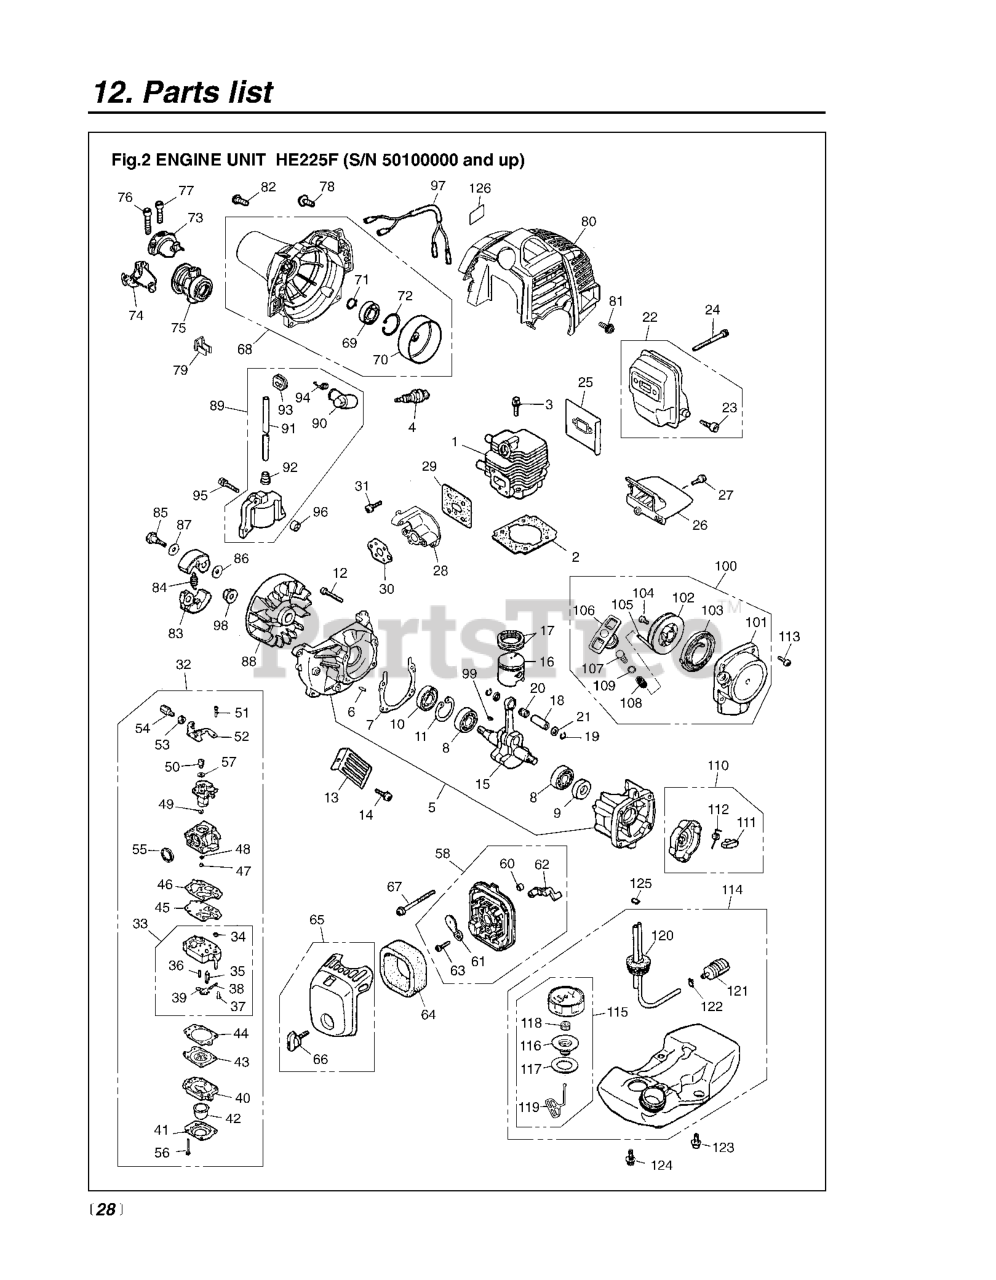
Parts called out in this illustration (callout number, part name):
1	CYLINDER
6	PIN
10	SEAL
15	CRANKSHAFT R-42000&1850-42000)
17	RING
18	PIN.PISTON
22	MUFFLER-A
23	ARRESTER
24	BOLT, M5 x 50 (RPLS 125230550)
26	PLATE.MUFFLER
28	INSULATOR
32	CARBURETOR WYJ-113-1
33	CARBURETOR BODY
34	SCREEN
35	VALVE INLET
41	1OVER
43	DIAPHRAGM
45	DIAPHRAGM
46	GASKET
49	RING
50	SWIVEL
51	SCREW
52	BRACKET
53	NUT
54	ADJUSTER
55	RING PACKING
57	WASHER
58	BODY-A
61	PLATE.CHOKE
63	SCREW
65	COVER ASSEMBLY
69	BEARING
73	BRACKET (A) (RPLS T170031211)
74	BRACKET (B)
76	BOLT, M5 x 22
77	BOLT M5 X L10 ALLEN BOLT
89	COIL-A
92	CAP
93	GROMMET
96	SPACER
97	CORD COMP
98	NUT
99	KEY
100	RECOIL-A
103	SPRING, SPIRAL
104	SCREW
107	COLLAR (RPLS T160075320)
110	PULLEY-A
114	TANK ASSY (RPLS T170085000)
115	CAP-A
116	HOLDER-A
120	PIPE COMPLETE
122	CLIP
125	CLIP
126	LABEL
